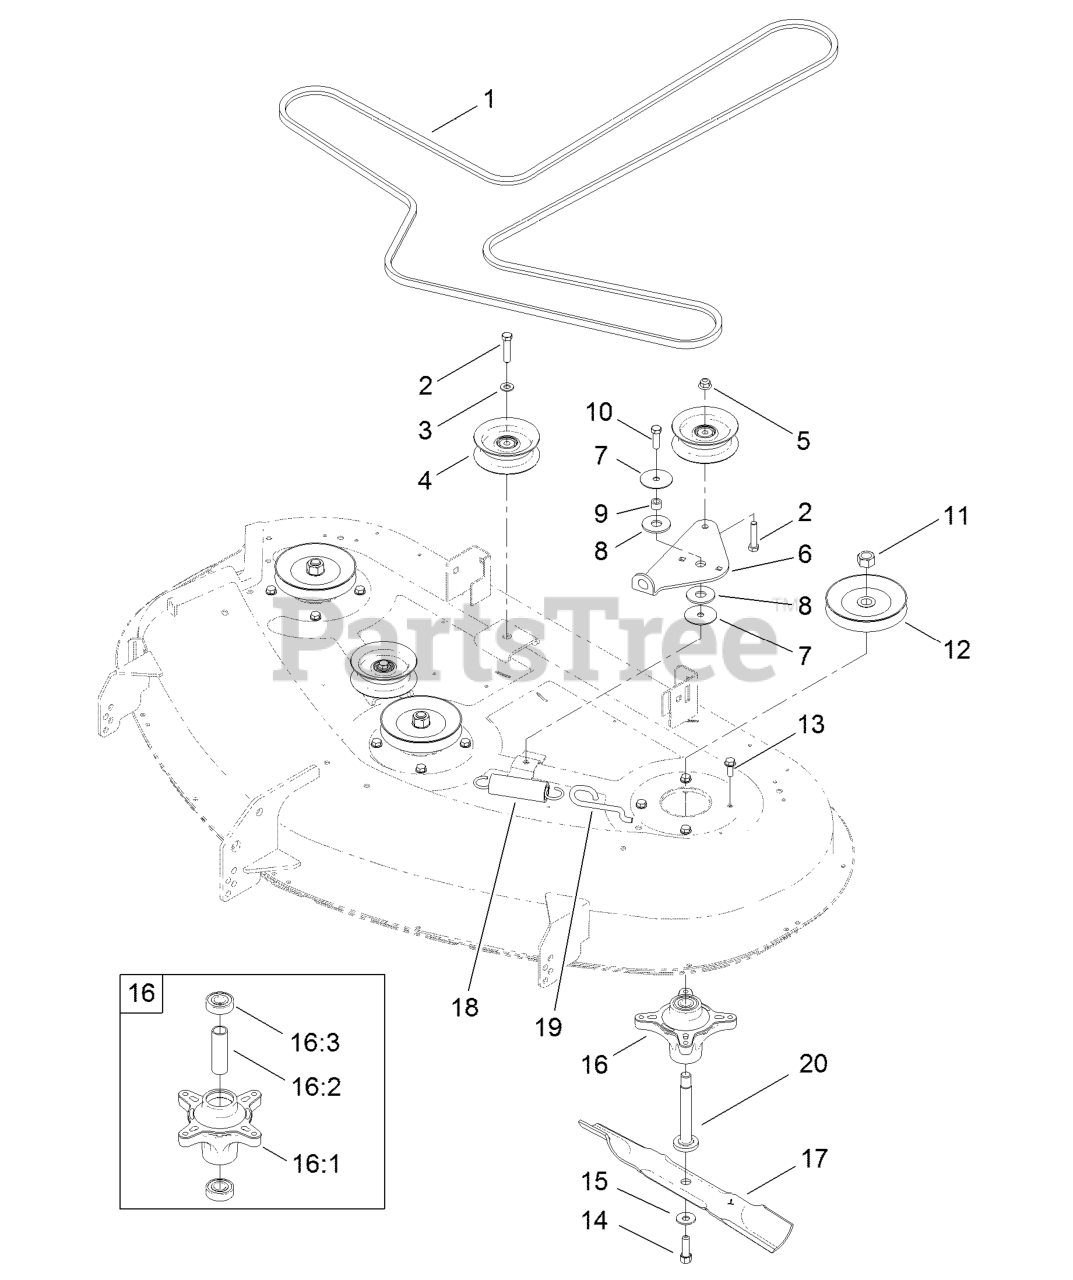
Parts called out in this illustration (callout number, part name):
1	V-BELT
2	SCREW-HH
3	WASHER-FLAT
5	NUT-HF, NI
6	ARM-IDLER
8	WASHER-FRICTION, COMPOSIT
10	SCREW-HH
11	NUT-HEX
13	SCREW-TAPTITE
14	SCREW-HH
15	WASHER-BELLEVILLE
17	BLADE-HI LIFT
18	SPRING-EXTENSION
19	HOOK-RETURN, SPRING
20	SHAFT-SPINDLE
